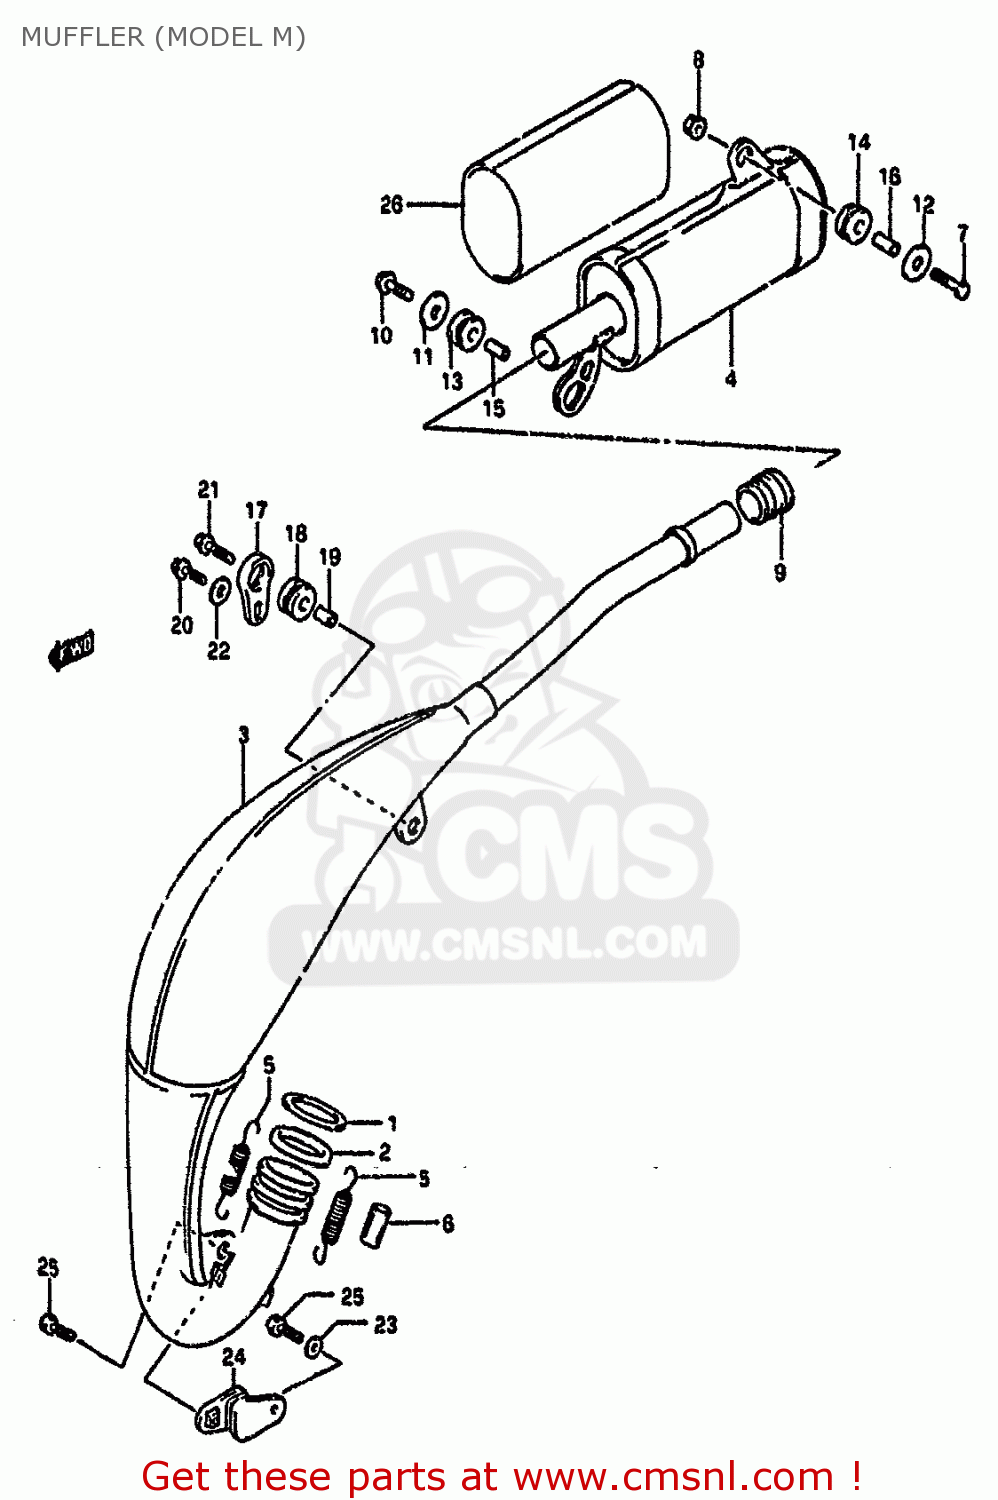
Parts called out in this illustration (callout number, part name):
1	WASHER,EXHAUST PIPE
2	O RING,EXHAUST PIPE
3	BODY,MUFFLER,FIRST
4	BODY,MUFFLER
5	SPRING
6	HOSE
7	BOLT
8	NUT
9	CONNECTOR,MUFFLER
10	BOLT
11	WASHER (6.5X24X1.2)
12	WASHER(8.5X26X1.2)
13	CUSHION
14	CUSHION
15	SPACER (6.8X10X9)
16	SPACER (8.1X11.5X13)
17	PLATE,MUFFLER MTG
18	CUSHION,MUFFLER
19	SPACER (6.4X9X13.5)
20	BOLT
21	BOLT
22	WASHER (6.5X20X1.2)
23	WASHER
24	DAMPER,MUFFLER SUPPORT
25	BOLT
26	SILENCER,MUFFLER
